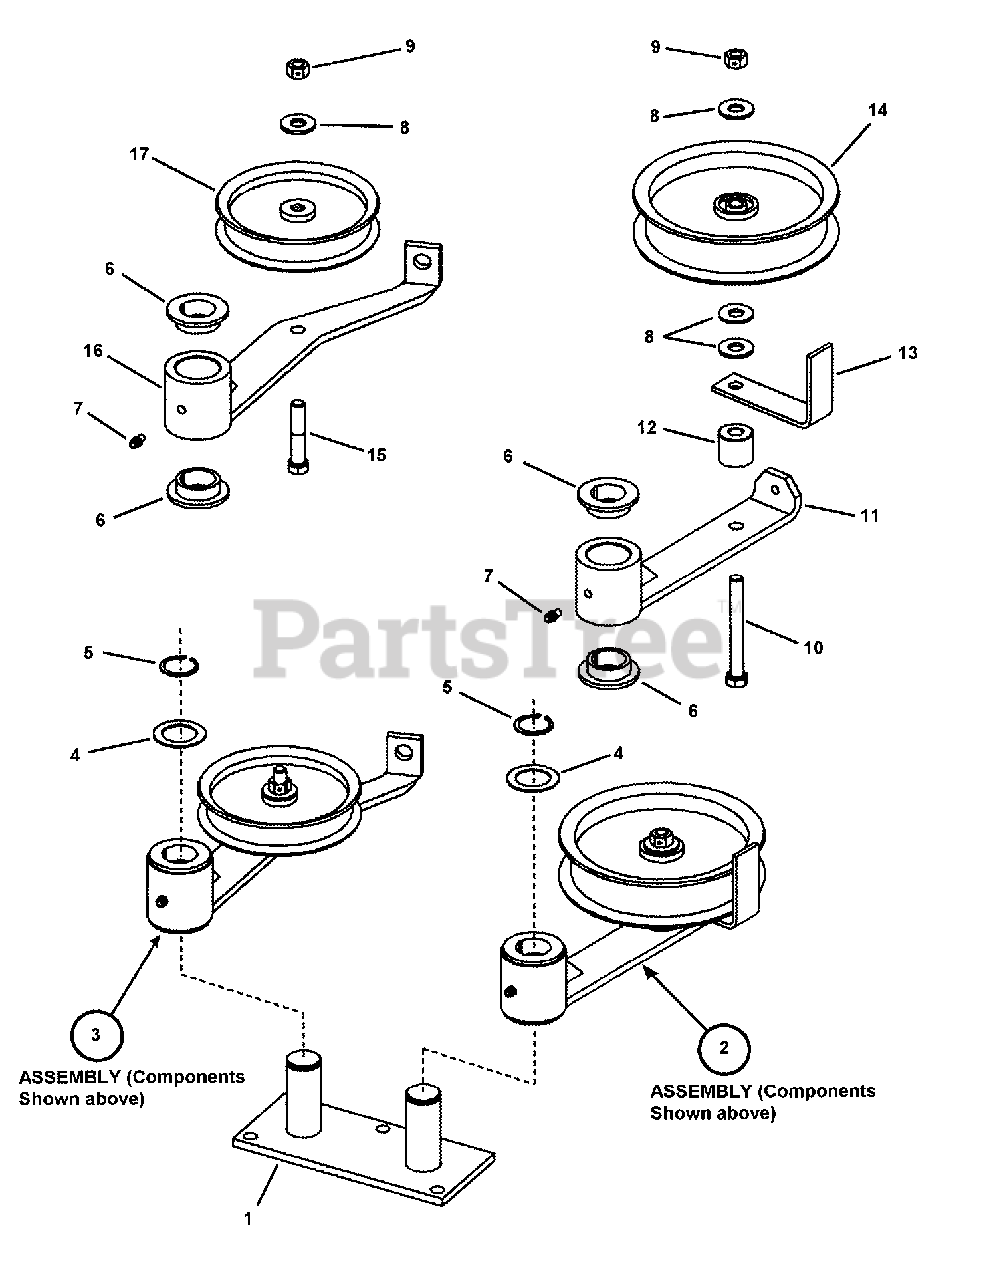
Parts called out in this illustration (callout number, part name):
1	WELDMENT, Idler Plate
2	ASSEMBLY, Primary Idler
3	ASSEMBLY, Secondary Idler
4	BUSHING, 1" Machine
5	RING, 1" External Retaining
6	BUSHING, Idler (Powdered Metal)
7	LUBE FITTING, 3/16"
8	WASHER, 3/8" USS
9	NUT, 3/8-16 Hex Center Lock, GR 5 or B
10	SCREW, 3/8-16 x 3-1/4" Hex Head Cap, GR 5
11	WELDMENT, Primary Idler Arm
12	BUSHING - Idler
13	RETAINER, Idler Belt
14	PULLEY, Flat Idler
15	SCREW, 3/8-16 x 1-3/4" Hex Head Cap, GR 5
16	WELDMENT, Secondary Idler Arm
17	PULLEY, Idler
